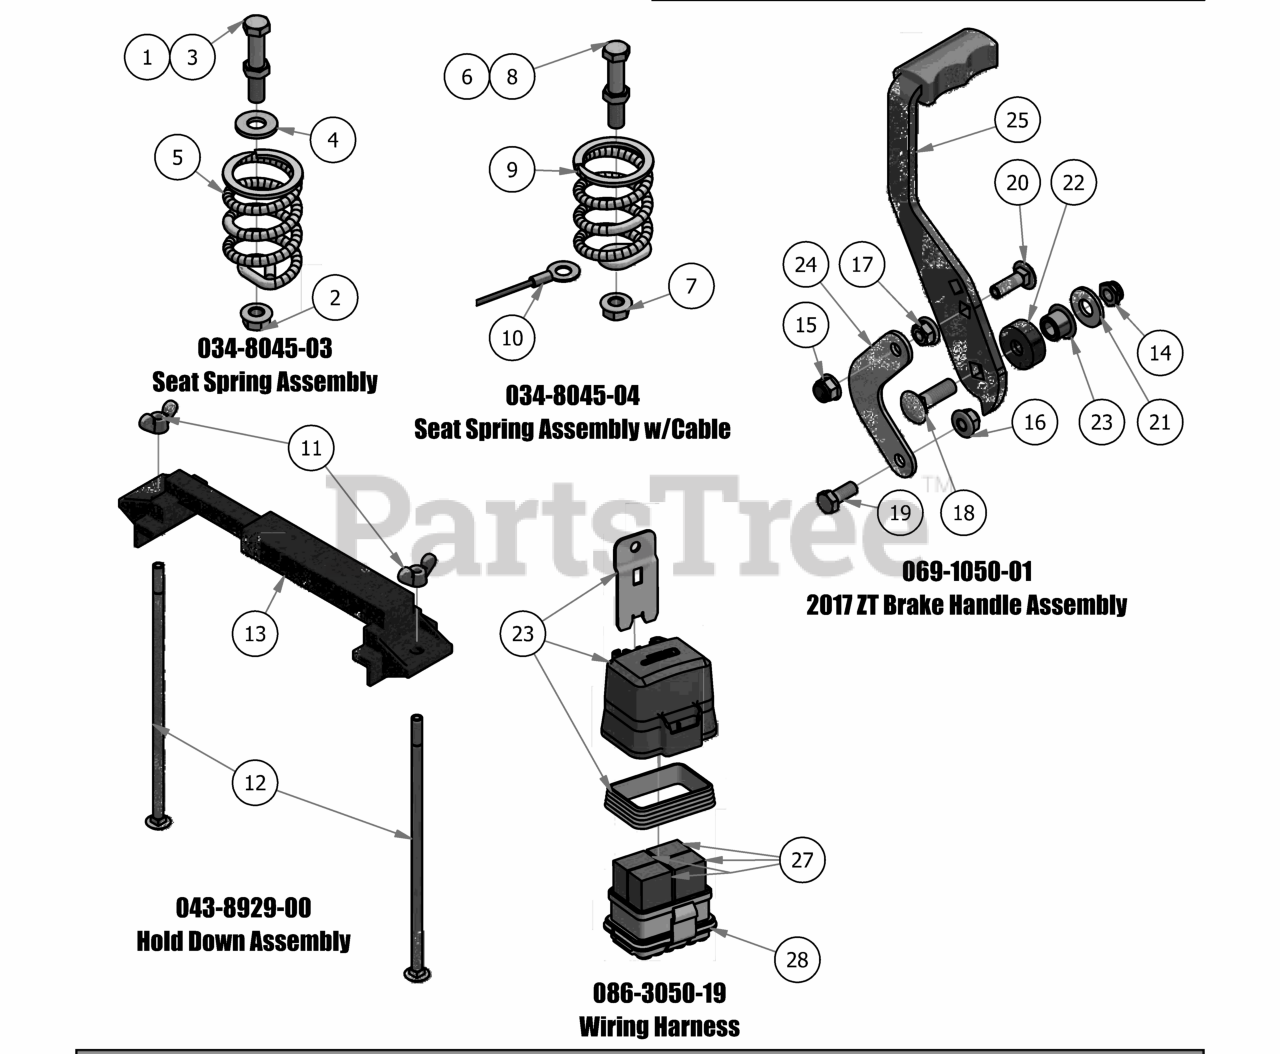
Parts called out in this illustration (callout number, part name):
1	3/8-16 Half Jam Nut
2	3/8" Flange Nut
3	3/8"-16 x 2" Gr 5 Hex Bolt
4	3/8" Flat Washer
5	Seat Spring
6	3/8-16 Half Jam Nut
7	3/8" Flange Nut
8	3/8"-16 x 2" Gr 5 Hex Bolt
9	Seat Spring
10	Seat Cable
11	1/4" Wing Nut
12	1/4-20 X 8 Carriage Bolt
13	Battery Hold Down
14	3/8-16 Centerlock Half Nut
15	5/16-18 Nylon Insert Flange Nut (Black Cap)
16	5/16" Nylon Flange Nut
17	5/16" Flange Nut
18	3/8" x 1 1/4" Carriage Bolt
19	5/16" x 3/4" Hex Bolt
20	5/16" x 1" Carriage Bolt
21	3/8" Flat Washer
22	2015 Brake Lever Spacer
23	Bronze Bushing SF-1220-8
23	Relay Block Cover Replacement Kit
24	Brake Cable Adapter Bracket
25	Brake Handle
28	Wiring Harness (Includes Cover Replacement Kit and Relays)
